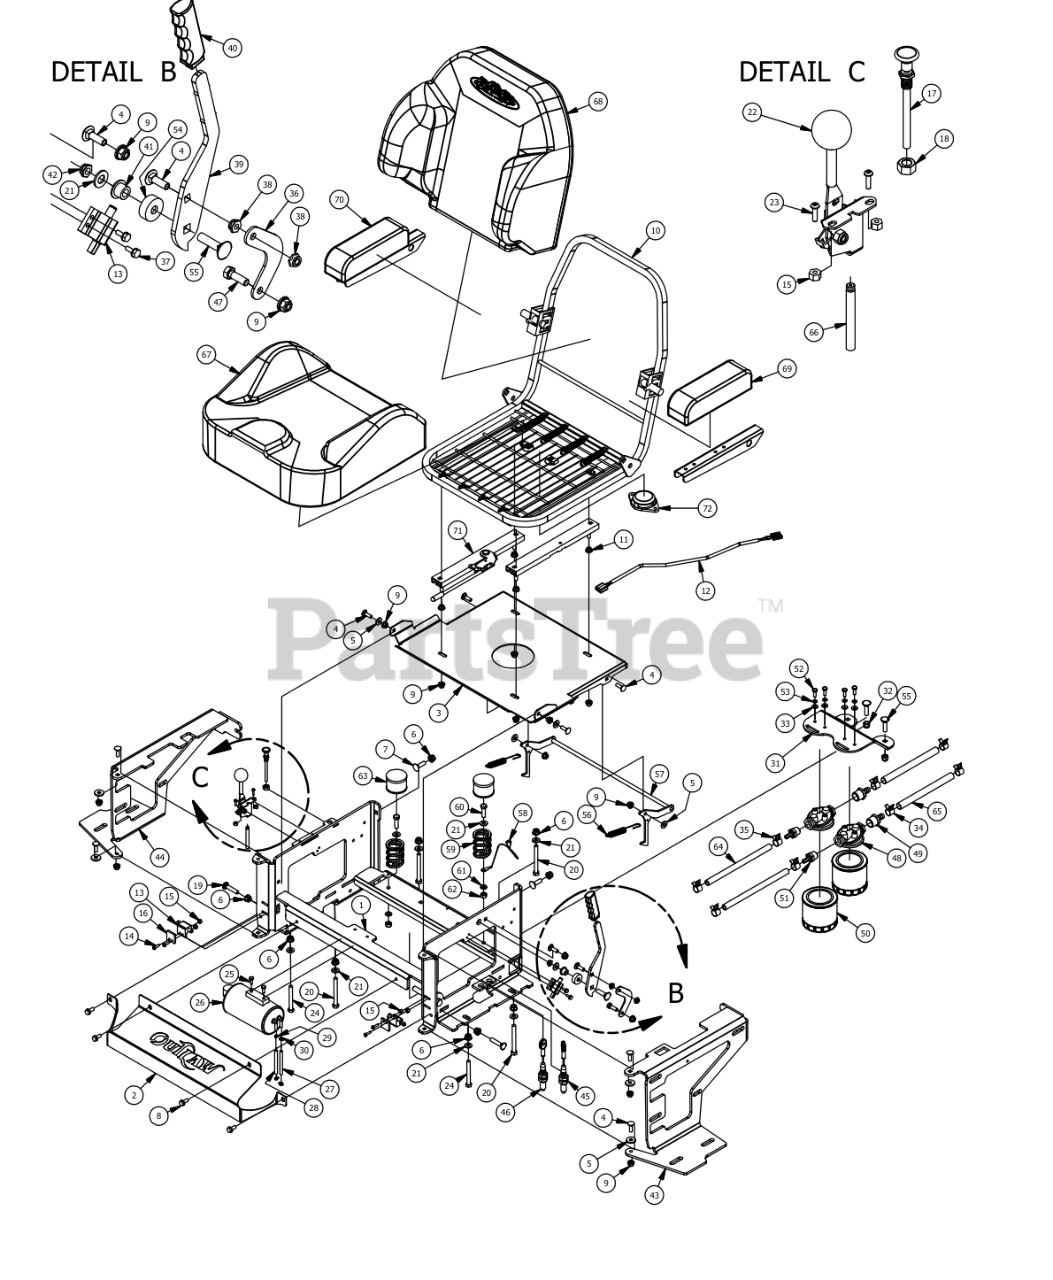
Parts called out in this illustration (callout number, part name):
1	2016 Outlaw Seat Bracket
2	Outlaw Cooler Cover
3	2016 Seat Plate Outlaw
4	5/16" x 1" Carriage Bolt
5	.360 ID Plastic Washer
6	3/8" Nylock Flange Nut
7	3/8" x 1 1/4" Carriage Bolt
8	5/16 x 3/4 washer head type F screw
9	5/16" Nylock Flange Nut Zinc
10	2015 Outlaw Seat
11	5/16" Flange Nut
12	Seat Switch Adapter
13	Safety Switch
14	10-24 x 1 BS C/S 18-8 SS
15	10-24 Nylon Insert Locknut
16	Switch Block Plastic
18	3/8" Fine Threaded Jam Nut
19	3/8 x 1 3/4 Carriage Bolt
20	3/8-16x3-1/2 grade 5 hex bolt
21	3/8" Flat Washer
22	Universal Throttle Head - 2012
23	10-24 X 5/8 BS Button Head Bolt
24	3/8-16x3 grade 5 hex bolt
25	M6-1.0 X 16MM Hex Bolt
26	Carbon Canister
27	1/4" Vinyl Tubing
28	3/16 Vinyl Tubing
29	3/16" Vinyl Hose Clamp
30	3/16 Vinyl Clamp
31	Outlaw Filter Bracket
32	3/8 Nylock Nut
33	1/4" Flat Washer
34	1/2 Hose Clamp
35	3/8" Hose Clamp
36	Brake Cable Adapter Bracket
37	12-24x 1/2 HWH Bolt
38	5/16-18 Nylock Jam Nut 1/2 Nut
39	Brake Handle Cam Over
40	Rubber Brake Grip-CZT/ZT 2013
41	Bronze Bushing SF-1220-8
42	3/8-16 Hex Flange Top L/N
43	Outlaw 2016 Tank Support (Left)
44	Outlaw 2015 Tank Support (Right)
45	2015 XP Brake Cable - Long
46	2015 XP Brake Cable - Short
47	5/16" x 1" Bolt
48	Filter Head-Hydraulic Filter
49	Filter Head Fitting 1/2 x 1/2
51	1/2" Pipe to 3/8" Barb
52	1/4" x 3/4" Hex Bolt
53	1/4" Lock Washer
54	2015 Brake Lever Spacer
55	3/8 x 1 1/2 Carriage Bolt
56	Brake Spring
57	Seat Latch Rod Assembly 2016 XP
58	Seat Cable
59	Seat Spring
60	3/8" x 1 1/4" Hex Bolt
61	3/8" Lock Washer
62	3/8" Hex Nut
63	Spring Cap Cover
64	3/8" Clear Hose
65	1/2 Clear Braded Hose Priced/Foot
66	Outlaw Throttle Cable (Cable Only)
67	Extreme/XP Outlaw Seat Cushion - Bottom
68	Extreme/XP Outlaw Seat Cushion - Back
69	Extreme/XP Outlaw Seat Arm Pads Only (Pair)
70	Extreme/XP Outlaw Seat Arm Rest (Pair)
71	Extreme/XP Outlaw Seat Rails
72	Seat Switch
